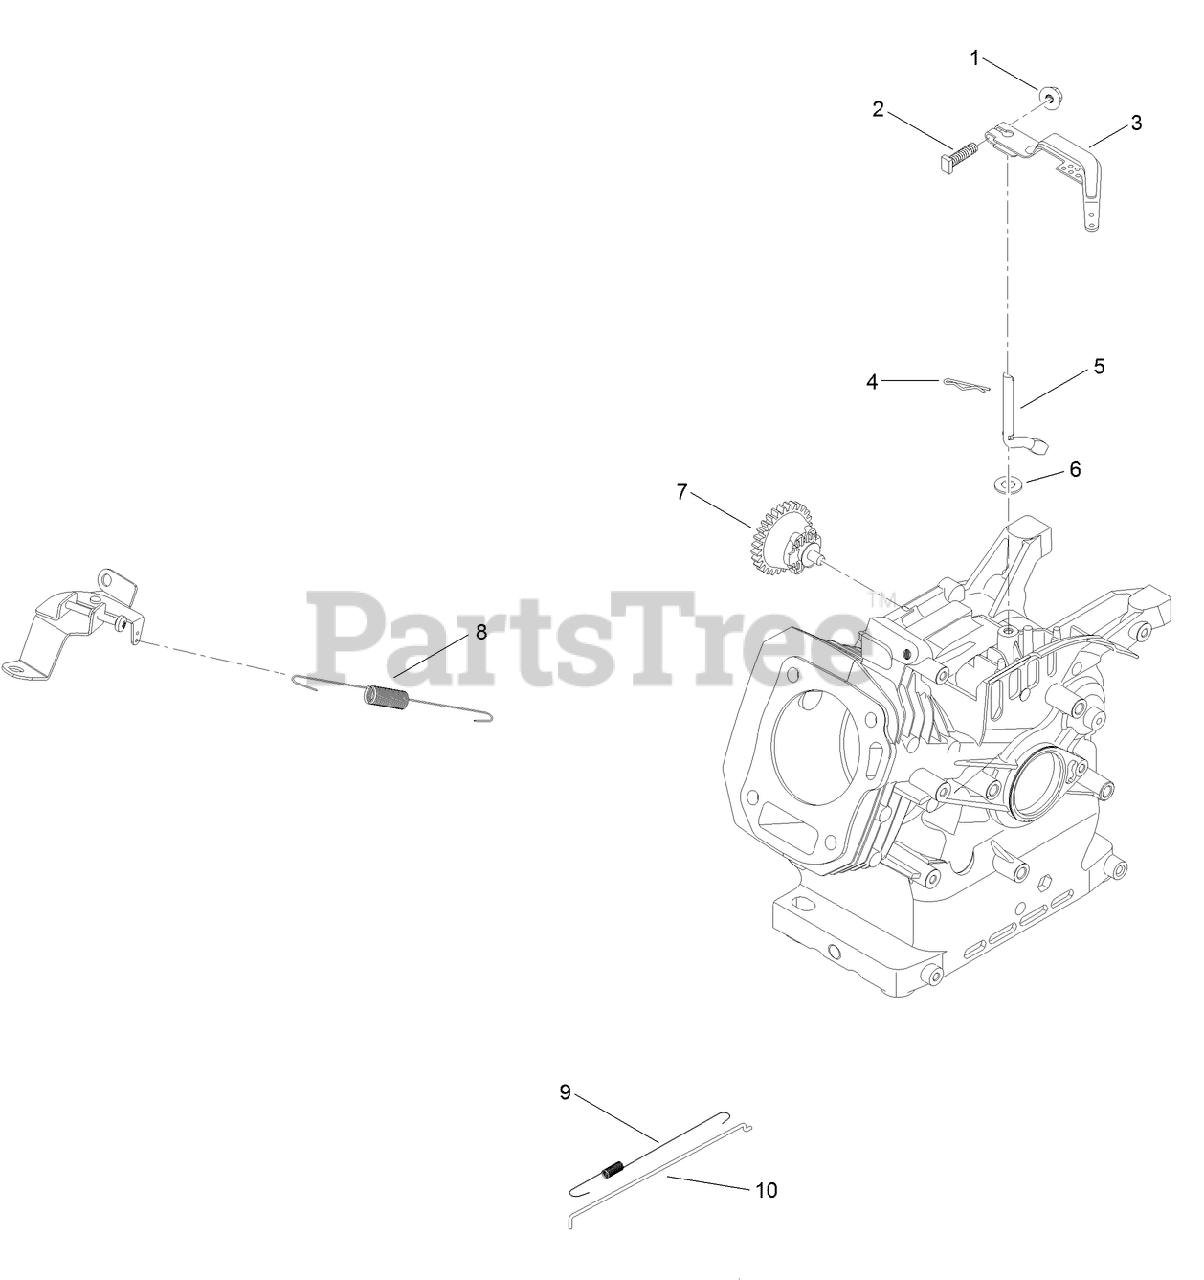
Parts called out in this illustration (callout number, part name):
1	NUT-FLANGE
2	BOLT-ARM, GOVERNOR
3	ARM-GOVERNOR
4	PIN-HAIR
5	SHAFT-GOVERNOR
6	WASHER-PLAIN
7	GOVERNOR GEAR ASM
8	SPRING-GOVERNOR
9	SPRING-RETURN, THROTTLE
10	ROD-GOVERNOR
